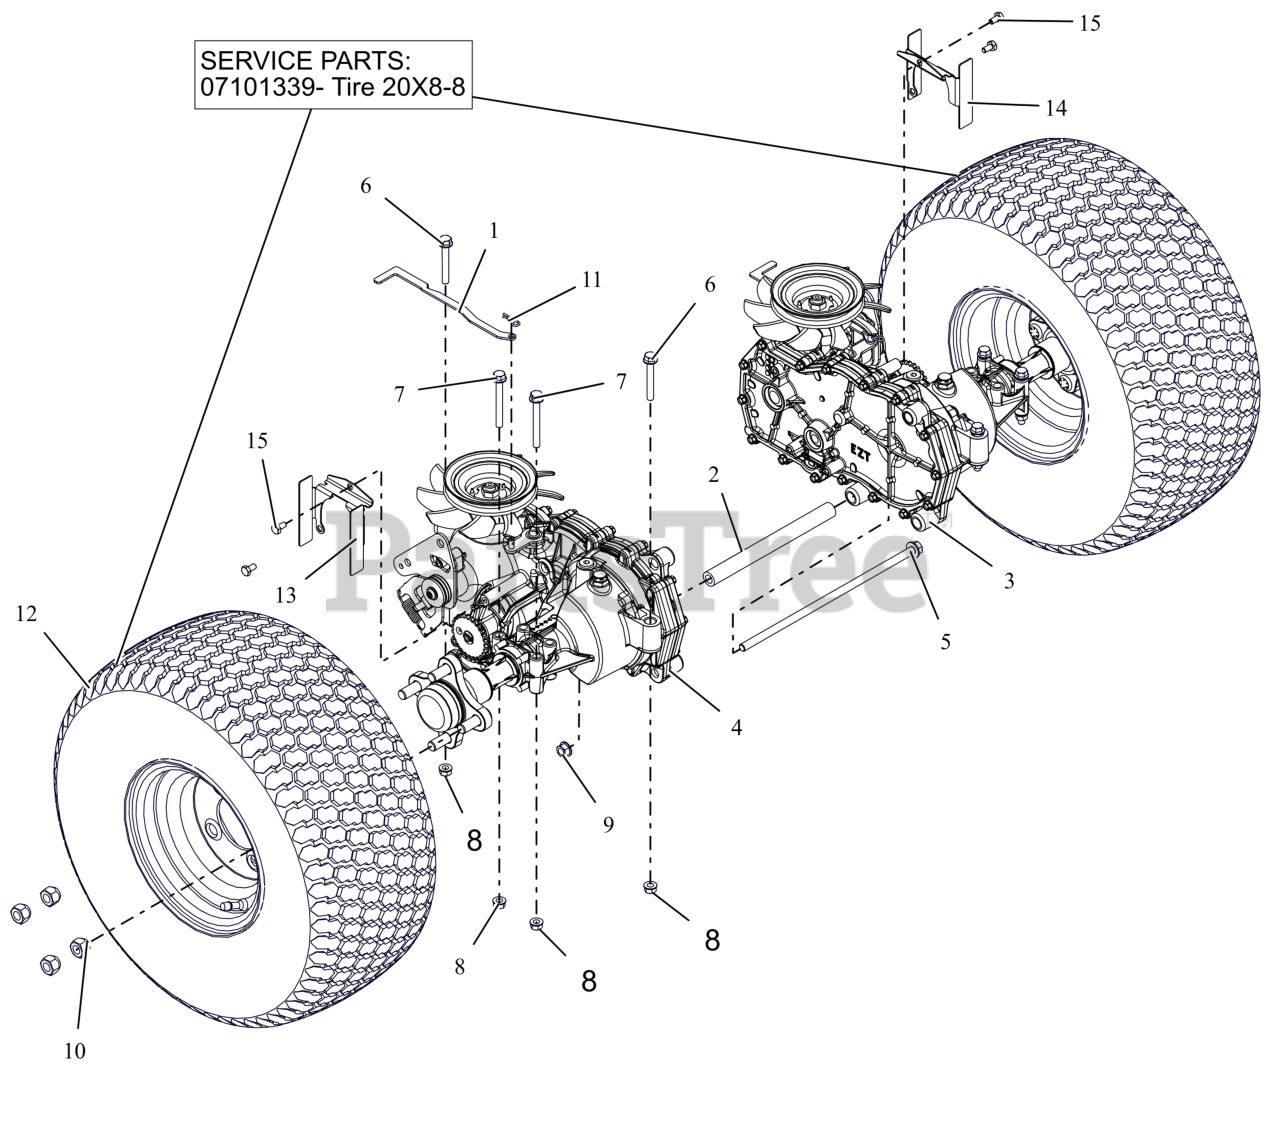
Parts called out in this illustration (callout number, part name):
1	BRKT, DUMP VALVE
2	TUBE, TRANSAXLE BRACE 8.18LG
3	TRANSAXLE
4	TRANSAXLE
5	BLT,HEX-FLG .38-16X11.5 G5 ZCC
6	BLT,HEX-FLG .31-18X2.25 G5 ZCC
7	BLT,HEX-FLG .31-18X2.75 G5 ZCC
8	NUT,LK-CTR-FLG .31-18 GF ZCC
9	NUT-LK-CTR-FLG .375-16 GF ZCC
10	NUT, WHEEL .50-20 ZCC
11	PIN, HAIR #213 .08X1.19 ZCC
12	ASSM TIRE\WHEEL, 20 X 8 -8
12	TIRE, 20 X 8-8
13	GUARD, PARKING BRAKE RH
14	GUARD, PARKING BRAKE LH
15	BLT,HEX .25-20X.50 G5 ZCC
